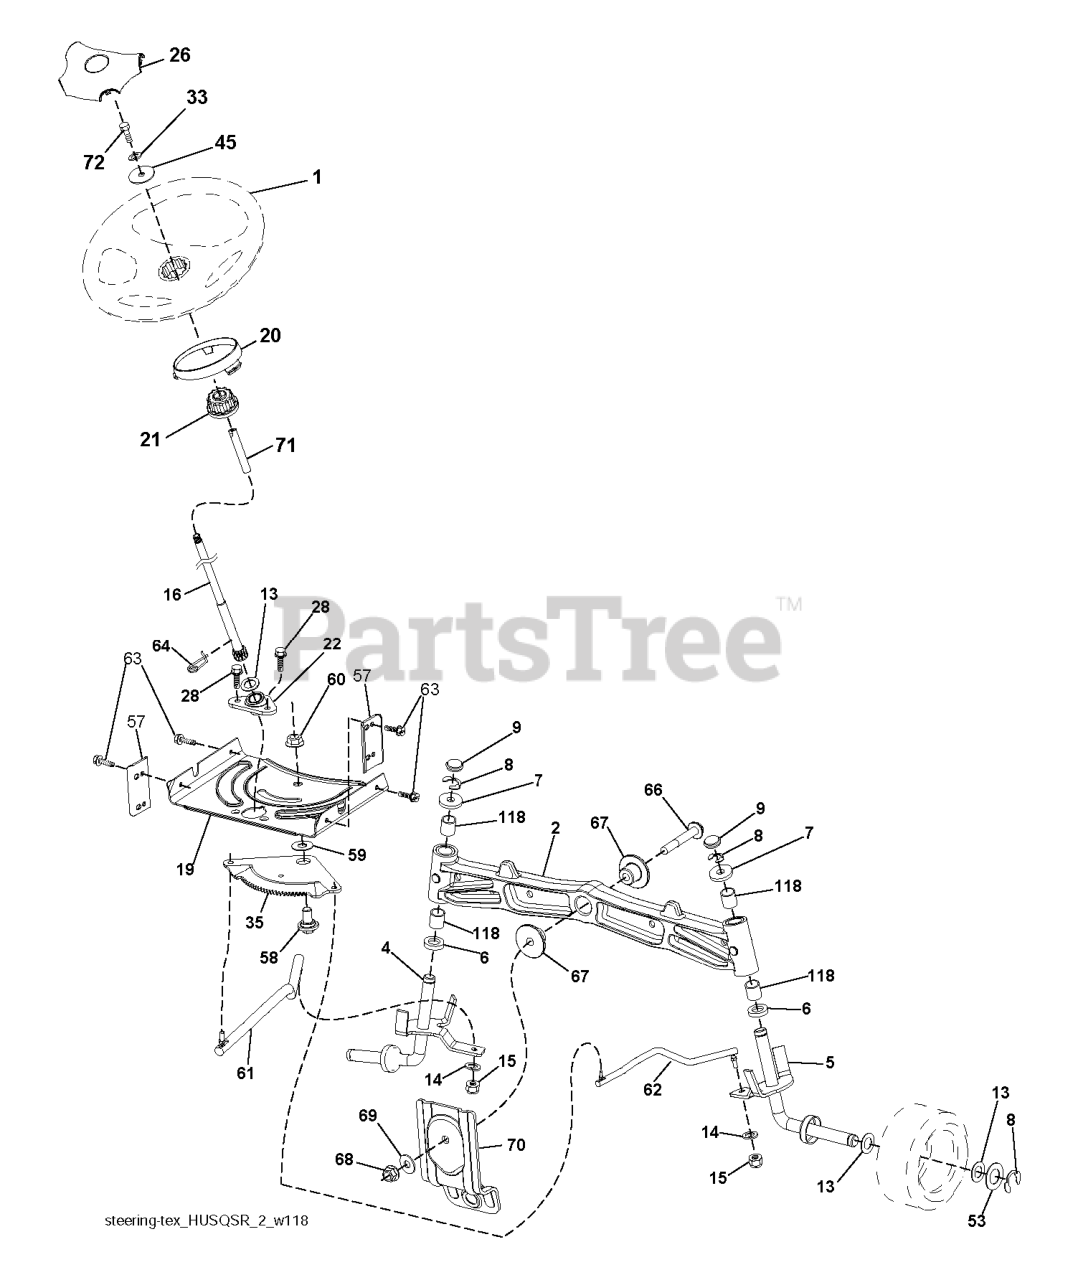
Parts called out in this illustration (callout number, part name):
1	RP WHEEL.STEER.HUSQ.PREM.OVMLD
2	AXLE.CAST.IRON
4	SPINDLE.WELDED.LH.15"TEX
5	SPINDLE.WELDED.RH.15"T
6	THRUST WASHER
9	CAP.SPINDLE.BLACK
14	WASHER, LOCK 3/8
15	NUT CROWNLOCK 3/8-24
16	SHAFT STEERING
19	PLATE.STEER.DDL.NLT/NG
20	BOOT, STEERING
21	ADAPTER, WHEEL STNG..
22	BUSHING.ASM.STEERING.A
26	RP INSERT.CAP.WHL.STRG.HUSQ.
28	SCREW, 3/8-16X3/4
33	WASHER.LOCK.HVY.HLCL.SPR.5/16
35	GEAR.SECTOR.PLATE.DDL.
45	WASHER.11/32
53	WASHER.HARDENED
57	BRACKET.UPSTOP.TEX
58	BOLT.SHOULDER.SECTOR.P
59	WASHER.THURST.SECTOR.S
60	NUT FLANGE LOCK 5/8-11
61	DRAGLINK.LH.BALLSTUD.D
62	DRAGLINK.RH.BALLSTUD.D
63	SCREW
64	RETAINER.CLIP.SPRING.S
66	BOLT HEX FGHD 7/16-14 X 3 SERR
67	BUSHING.PM.FRONT AXLE
68	NUT.LOCK.FLANGE.7/16
70	BRKT.DECK.SUSPENSION.F
71	SHAFT EXTENSION STEERING
72	BOLT YT
73	WASHER.1.5X.505X.118
118	BUSHING, AXLE CAST
